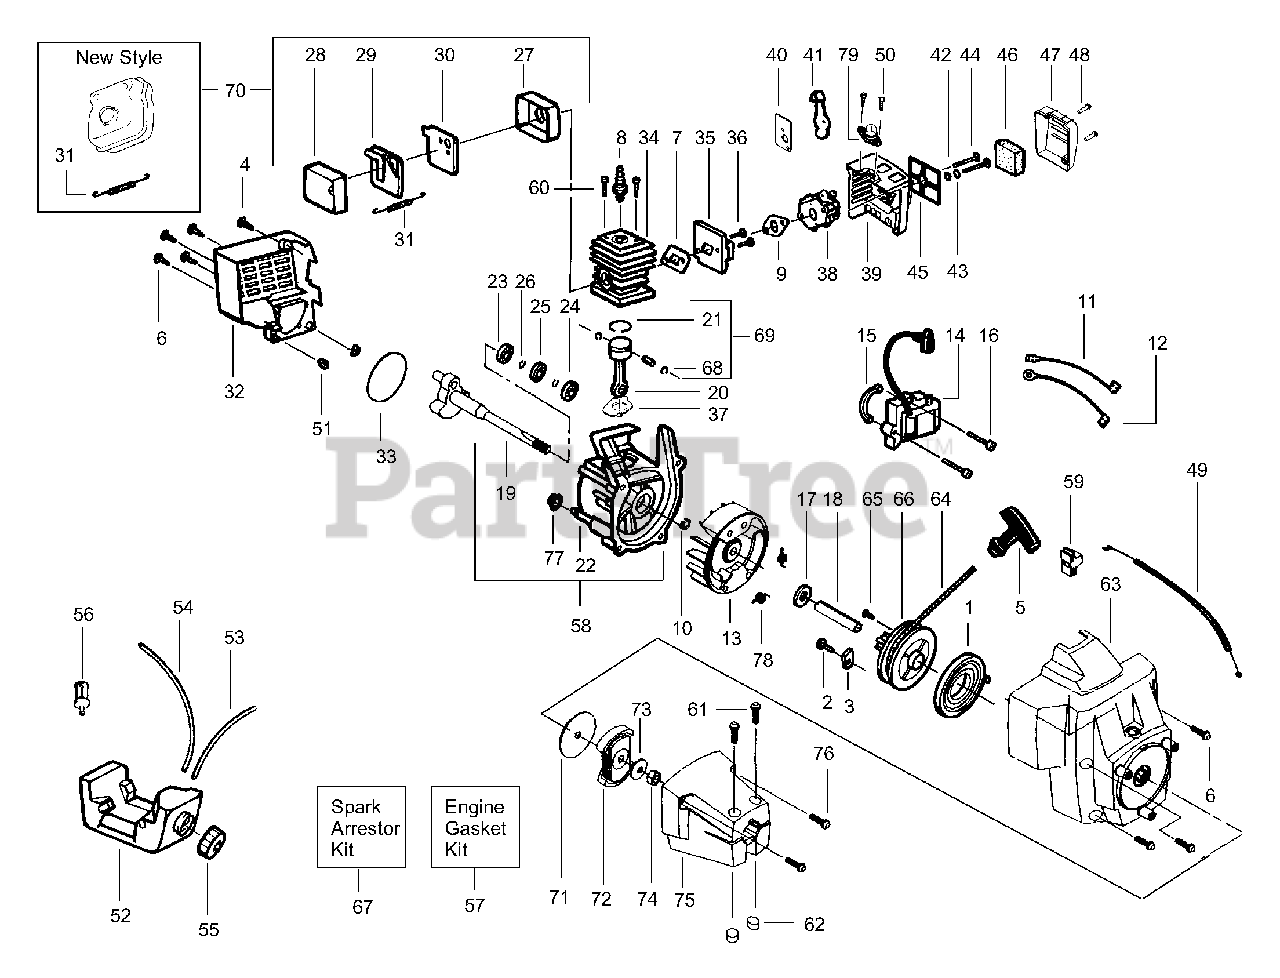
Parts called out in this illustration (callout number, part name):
1	Starter Spring
3	Retainer
5	Starter Handle
6	Screw
7	Gasket-Cylinder/Carb Adaptor (kit)
8	Spark Plug
9	Gasket (kit)
10	Retainer
11	Lead Wire
12	Ground Wire
13	Flywheel Ass'y.
14	Ignition Module
19	Crankshaft Ass'y.
20	Connecting Rod Ass'y.
21	Piston Ring
22	Crankcase Ass'y.
23	Inner Bearing
24	Outer Bearing
25	C'case Seal
26	Retaining Ring
27	Muffler Body
28	Muffler Cover
29	Muffler Baffle-Exit
30	Muffler Baffle-First
31	Muffler Spring Old Style
31	Muffler Spring New Style
33	O-Ring/Gasket (kit)
34	Cylinder
35	Carb. Adaptor Kit
37	Gasket (kit)
38	Carburetor Ass'y. (WT380)
40	Choke Plate
41	Choke Shutter
42	Wave Washer
43	Choke Spacer
45	Filter Plate
46	Air Filter Foam
47	Air Filter Cover
49	Throttle Cable Ass'y.
51	Isolator-Shroud
52	Fuel Tank Ass'y.
53	Fuel Line-Primer/Tank
54	Fuel Line-Carb/Tank
55	Fuel Cap Ass'y.
56	Fuel Pickup Ass'y.
57	Engine Gasket Kit
58	C'case & C'shaft Assy.
59	Switch Kit
63	Fan Housing
64	Rope Kit
66	Starter Pulley
67	Spark Arrestor Kit Old Style
67	Spark Arrestor Kit New Style
68	Piston Pin Retainer
69	Piston Kit
70	Muffler Kit Old Style
70	Muffler Kit New Style
72	Clutch Ass'y.
75	Clutch Hsg.
77	Isolator-Crankcase
78	Spring-Starter Dog
79	Bulb Ass'y.
